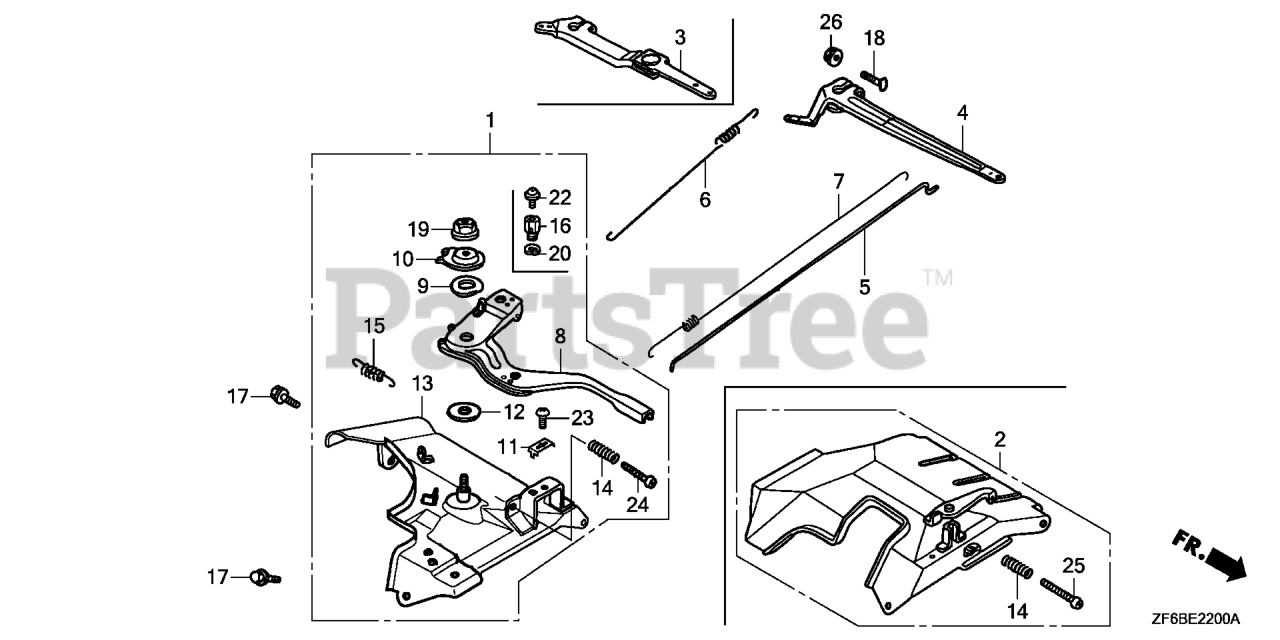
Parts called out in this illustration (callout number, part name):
1	CONTROL ASSY. (REMOTE)(ROD)
4	ARM, GOVERNOR
5	ROD, GOVERNOR
6	SPRING, GOVERNOR
7	SPRING, THROTTLE RETURN
8	LEVER, CONTROL
9	SPRING, LEVER
10	WASHER, CONTROL LEVER
11	HOLDER, CABLE
12	SPACER, CONTROL LEVER
13	BASE, CONTROL
14	SPRING, CONTROL ADJUSTING Use from Engine SN 2327377.
15	SPRING, CABLE RETURN
17	BOLT, FLANGE (6X12) (CT200)
18	BOLT, GOVERNOR ARM
19	NUT, SELF-LOCK (6MM)
23	SCREW, PAN (5X16)
24	SCREW, PAN (5X32)
26	NUT, FLANGE (6MM)
